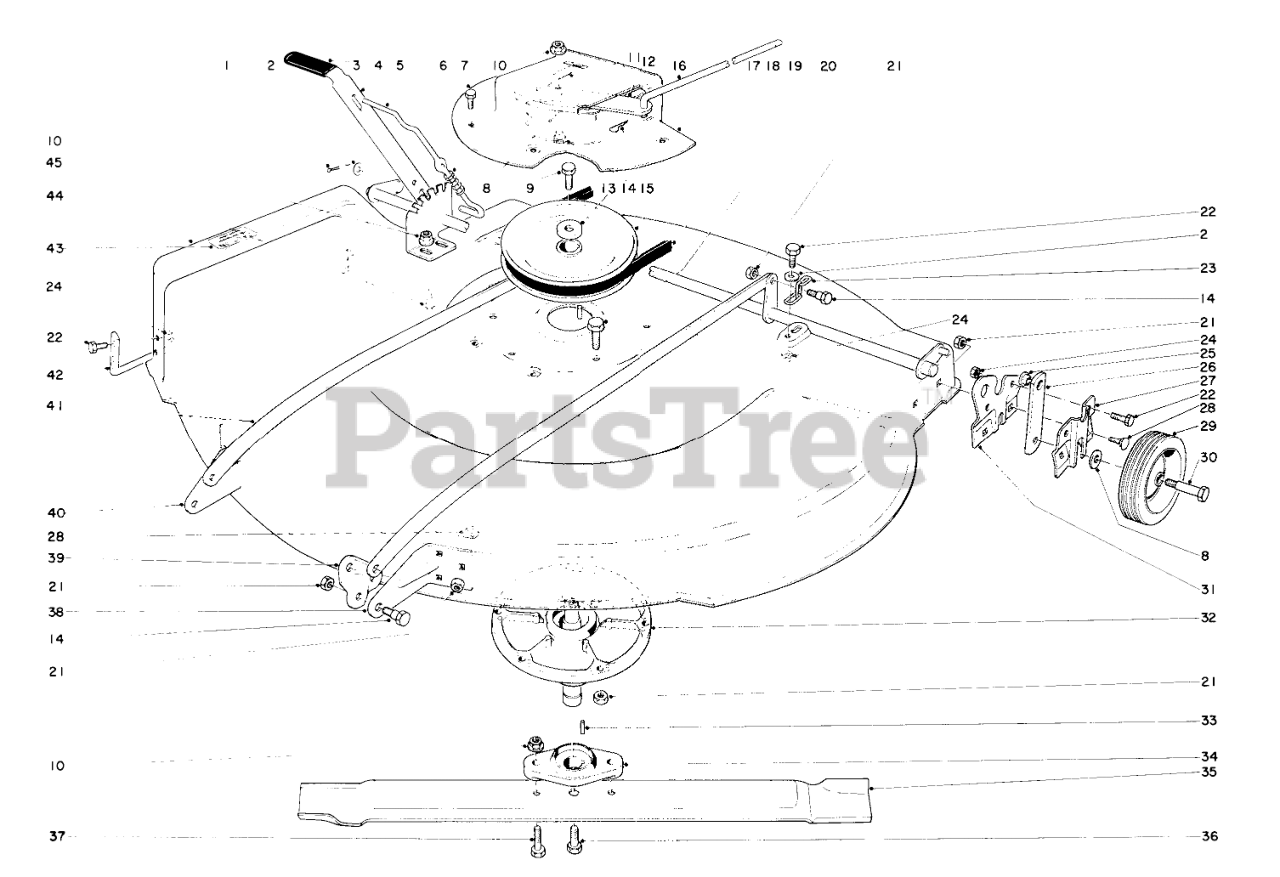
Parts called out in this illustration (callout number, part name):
1	PIN-COTTER
2	WASHER-FLAT
3	Grip Handle
4	Height Adj. Shaft
5	Latch Slide
6	Spring
7	SCREW-HWH
8	WASHER-FLAT
9	SCREW-HH
10	NUT-HF
11	Spring
12	Brake Lever
13	Washer
14	Screw
15	PIN-COTTER
16	Rod Blade Brake
17	Cover-Blade Housing
18	Pulley Blade
20	SCREW-HH
21	Nut
22	SCREW-HH
23	Chain
24	NUT-LOCK
25	Bushing
26	Slide Height Adj .
27	Retainer, Height Adj.
28	SCREW-CARR
29	Wheel
30	Screw
31	Bracket R. H.
32	BLD SPINDLE
33	Key
34	Adapter Blade
35	Cutter Blade
36	Capscrew
37	SCREW-HH
38	Bracket L. H.
39	Pivot
40	Bracket R. H.
41	Parallel Bar
42	Blade Rod
43	Decal
44	Housing
45	SCREW-HH
